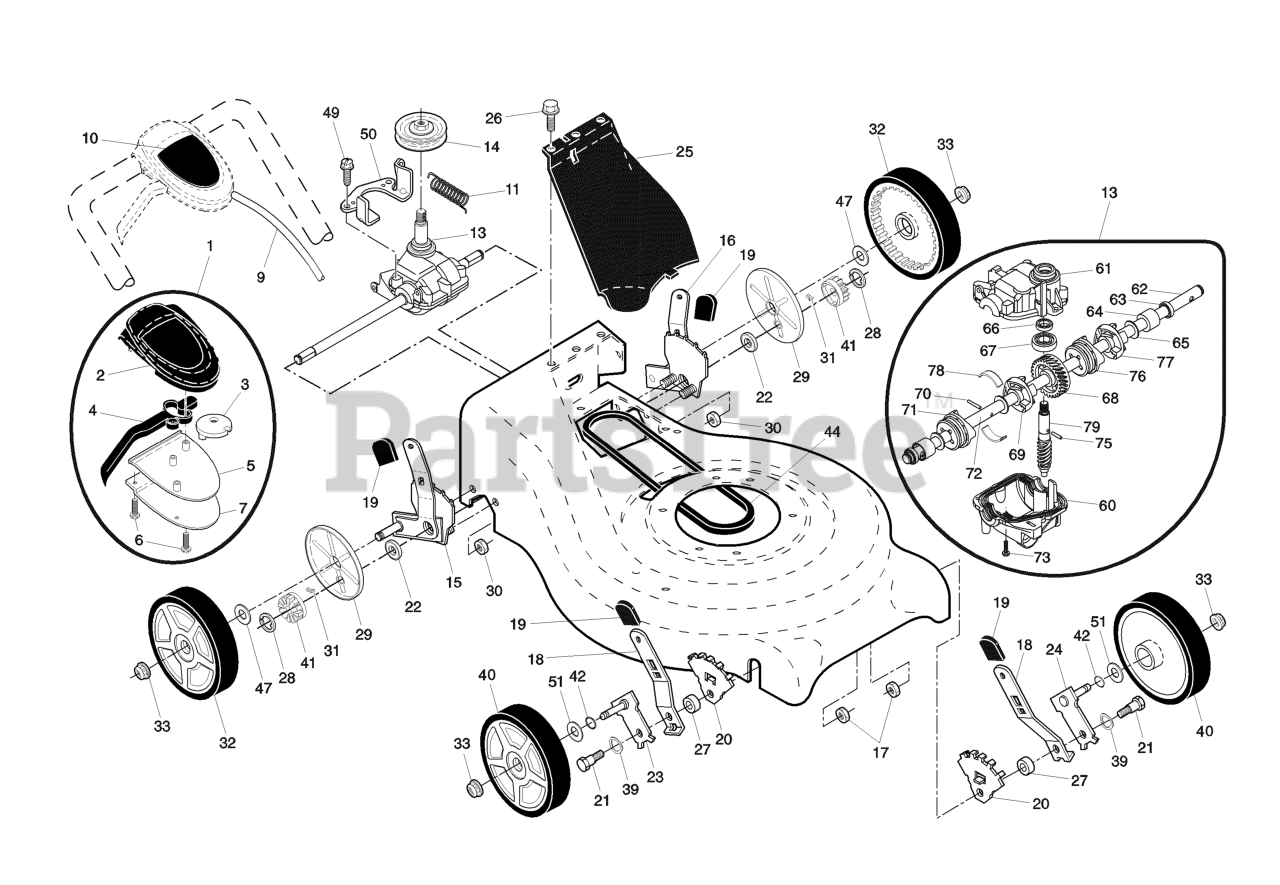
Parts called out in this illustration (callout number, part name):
1	DRIVE CONTROL ASSY, AUTO WALK
2	COVER.TOP.DRIVE.CONTROL.BLACK
3	PULLEY.CAM.DRIVE.CONTROL.EZ
4	LEVER, AUTOWALK DRIVE CONTROL
5	COVER.BOTTOM.DRIVE.CNTRL.BLACK
6	SCREW, PHILLIPS HEAD 10 X 5/8
7	BRACKET.DRIVE.CONTROL.MOUNT.BL
9	CABLE.ASSY.RGD.EZ.AUTO
10	DECAL, DRIVE
13	TRANSMISSION.21.RWGD
14	PULLEY.1.PIECE
15	KIT.ADJUSTER.ASM
16	KIT WHEEL ADJ LH
17	LOCKNUT 5/16-18
18	SELECTOR SPRING, FRONT
19	KNOB.DELUXE.GRAY
20	WHEEL ADJ BRACKET FRONT
21	SHOULDER BOLT 5/16-18
22	BEARING
23	AXLE ARM ASSY FRONT RH
24	AXLE ARM ASSY FRONT LH
25	COVER.DRIVE.21.RWGD.MO
27	SPACER.HEIGHT.ADJUSTER
28	E-RING 7/16 RE
29	COVER.DUST.WHEEL
30	LOCKNUT.NYLOC.1/4-20
31	PAWL, DRIVE
32	WHEEL.8X1.75.
33	NUT.HEX.FLANGE.3/8-16.LO(3 2)
34	PINIION.14.TOOTH.RGD
39	WASHER.CURVED.CYLINDRICAL
40	FRONT WHEEL AND TIRE ASSY 8X2
42	O-RING..070X.487.NEOPRENE
44	BELT.RGD.VS
47	WASHER FLUT
50	BELT KEEPER
51	WASHER.FLAT.1/2
60	CASE, LOWER
61	CASE UPPER
62	Shaft, Output, Long
63	SEAL.OUTPUT.SHAFT
66	SEAL INPUT SHAFT
68	GEAR 28 TEETH
69	DOG.FIXED.LH.32003
70	PIN 7 33732
71	DOG.MOVEABLE.LH.32005
72	Shaft, Output, Short
75	PIN 3.50.337 - 33733
76	DOG.FIXED.RH.32004
77	DOG.MOVEABLE.RH.32006
78	SPRING LEAF
79	SHAFT WORM
